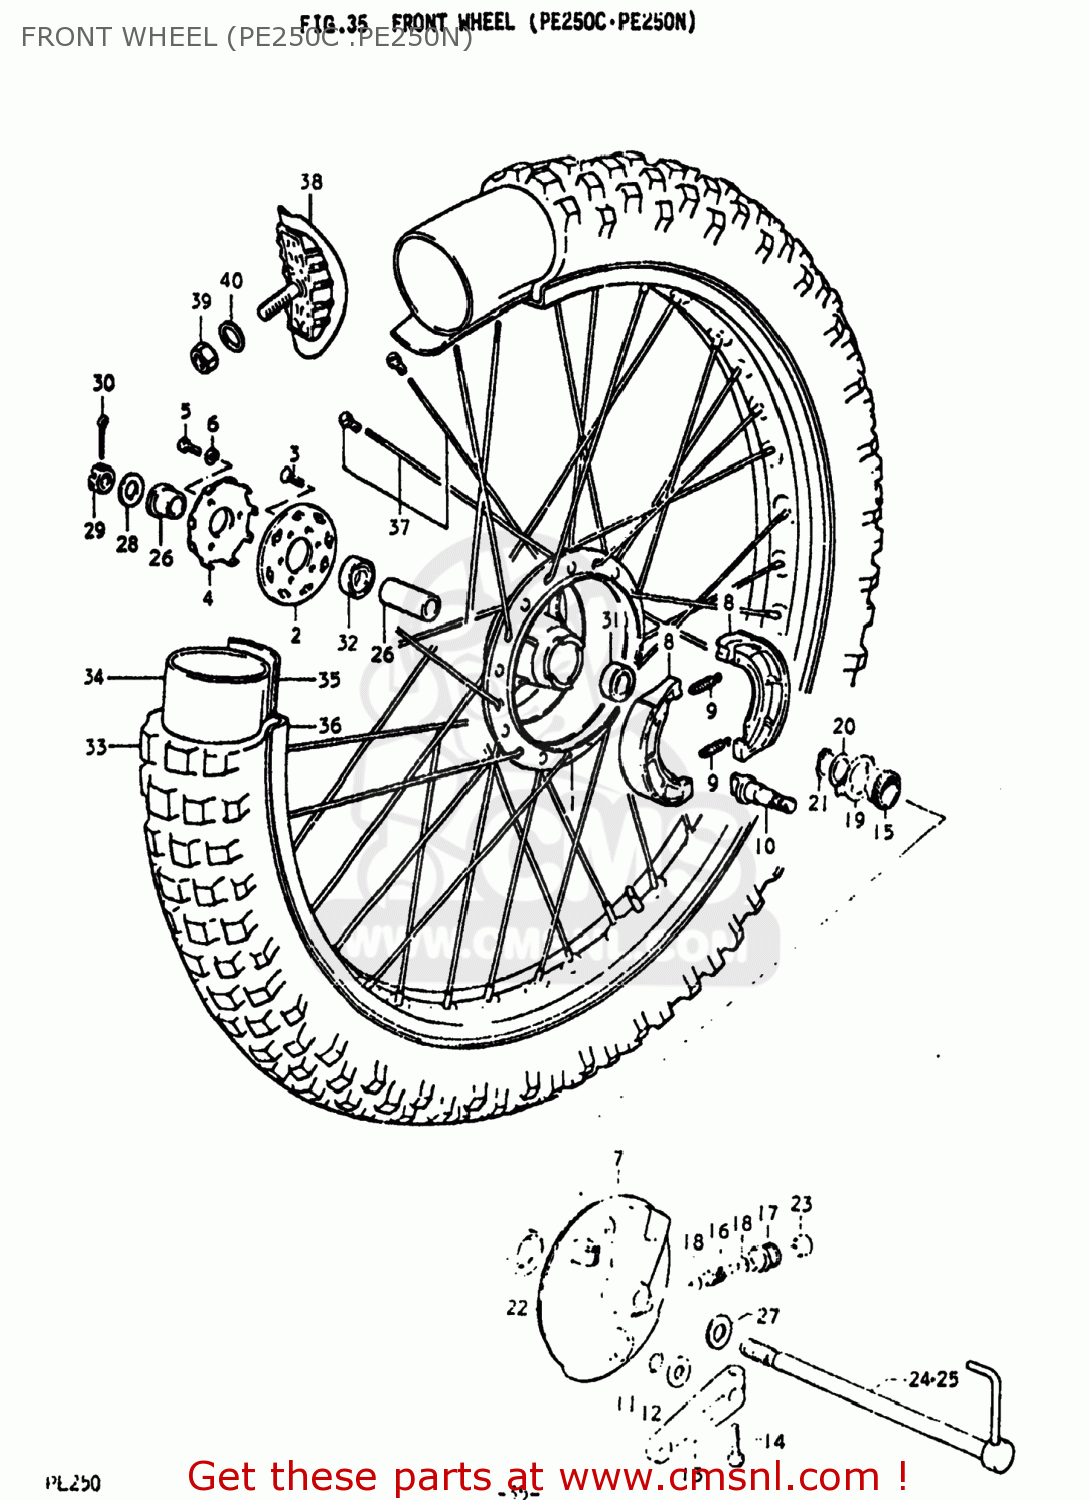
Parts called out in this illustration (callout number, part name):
1	DRUM,FRONT HUB
2	FLANGE,FR HUB,R
3	SCREW
4	RETAINER,FR HUB BEARING,R
5	BOLT, UPPER
6	LOCK WASHER
7	PANEL,FRONT HUB
8	SHOE,BRAKE
9	SPRING
10	CAM,FRONT BRAKE
11	O-RING,BOSS
12	WASHER (15X24X1.6)
13	LEVER,FRONT BRAKE CAM
14	BOLT
15	GEAR,SPEEDOMETER
16	PINION,SPEEDOMETER
17	BUSHING,SPEEDOMETER PINION
18	WASHER (5.1X9X0.4)
19	DRIVER,SPEEDOMETER GEAR
20	WASHER(22.5X27X1)
21	CIRCLIP
22	SEAL,OIL(26X38X4)
23	SEAL,OIL(6X10X3)
24	AXLE,FRONT
25	AXLE,FRONT
26	SPACER (12.6X19X52)
27	SPACER,FR AXLE,R
28	WASHER
29	NUT, REAR AXLE
30	COTTER PIN
31	BEARING
32	BEARING, RH
33	TIRE,FRONT
34	TUBE
35	PROTECTOR,WHEEL,INNER
36	RIM,FRONT WHEEL
37	SPOKE SET,FRONT
38	STOPPER,BEAD
39	NUT
40	WASHER
